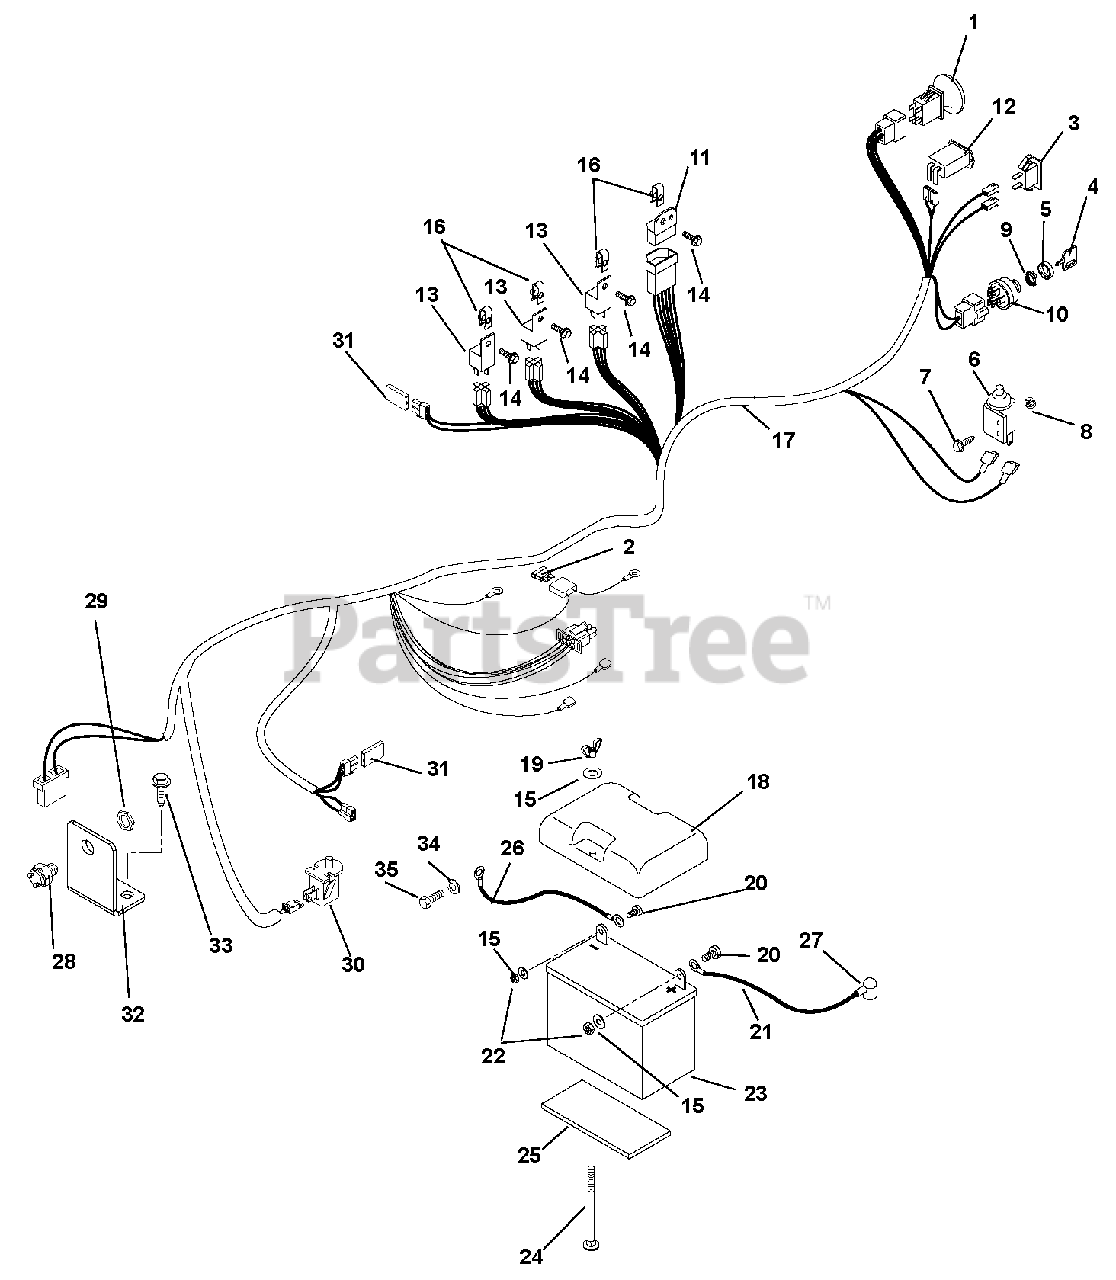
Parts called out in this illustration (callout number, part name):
3	1
7	2
8	2
12	1
13	AR
14	4
15	4
19	2
20	2
22	2
24	2
31	AR
33	2
34	1
35	1
